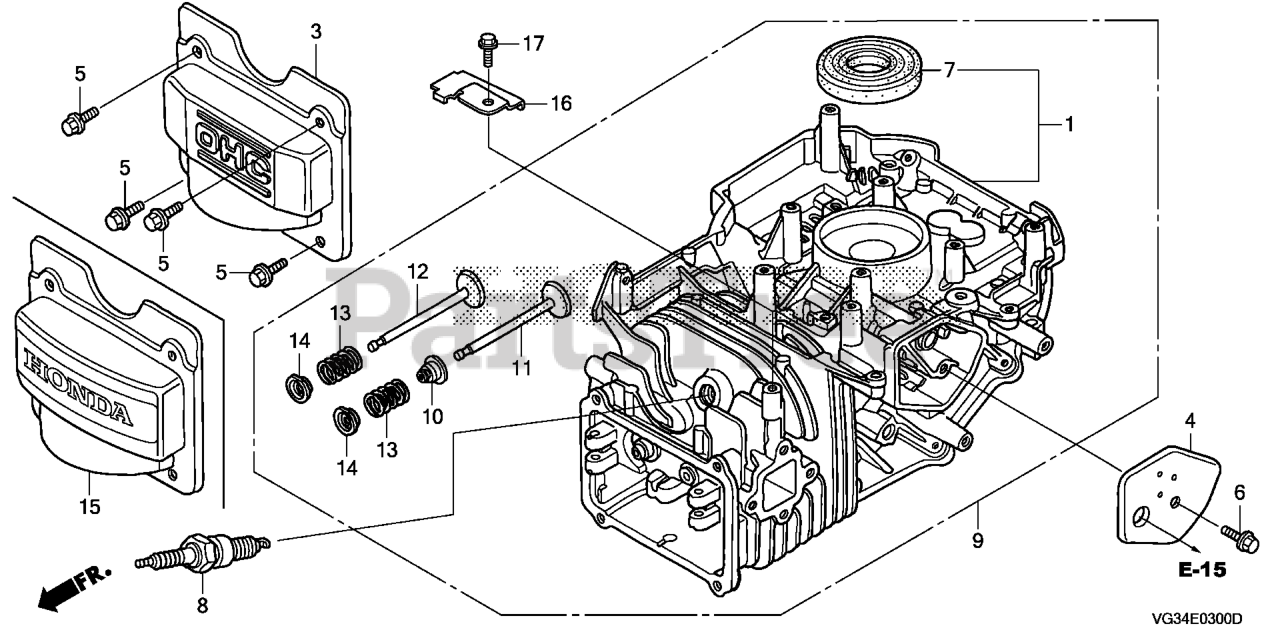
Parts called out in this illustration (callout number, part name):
1	CYLINDER ASSY.
4	COVER, BREATHER (Honda Code 5580006). (BREATHER VALVE ASSY.)
5	BOLT, FLANGE (6X12) (CT200)
6	BOLT, FLANGE (6X14)
7	OIL SEAL (25.4X62X6)
8	SPARK PLUG (BPR5ES) (NGK)
10	SEAL, VALVE STEM
11	VALVE, IN. (TECHNOSTAR)
12	VALVE, EX. (L8E)
12	VALVE, EX. (C8E)
13	SPRING, VALVE
14	RETAINER, VALVE SPRING
15	COVER, HEAD
16	BRACKET, REGULATOR
17	BOLT, FLANGE (6X14)
